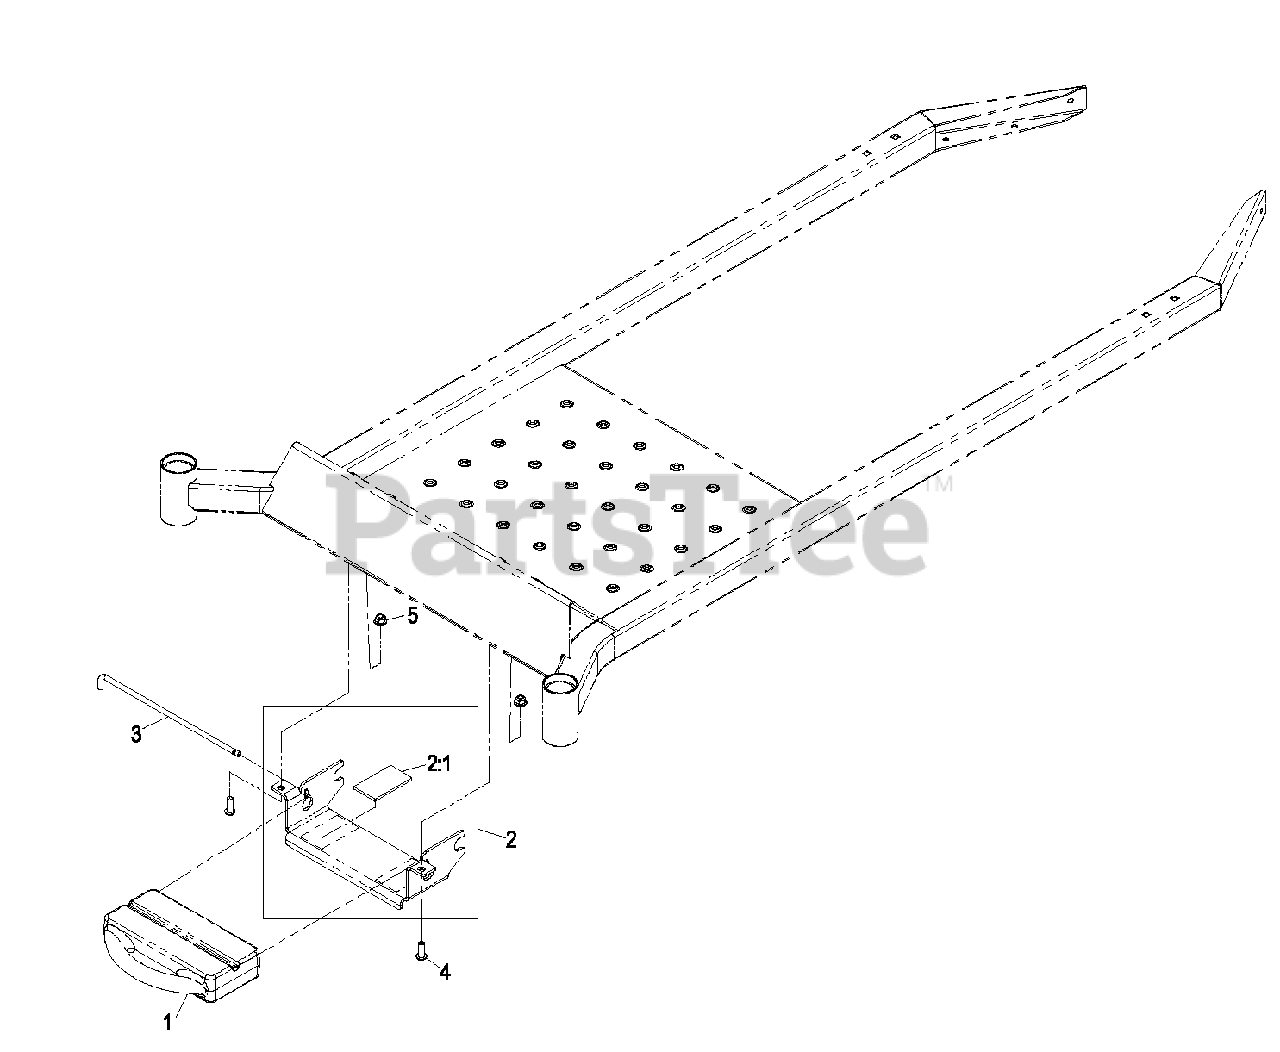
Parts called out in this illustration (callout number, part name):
1	WEIGHT-BAGGER, 25 LB
2	BRACKET AND BUMPER ASM
2:1	CUSHION-RUBBER
3	ROD-WEIGHT LOCK
4	SCREW-HSBH
5	NUT-HF, NI
